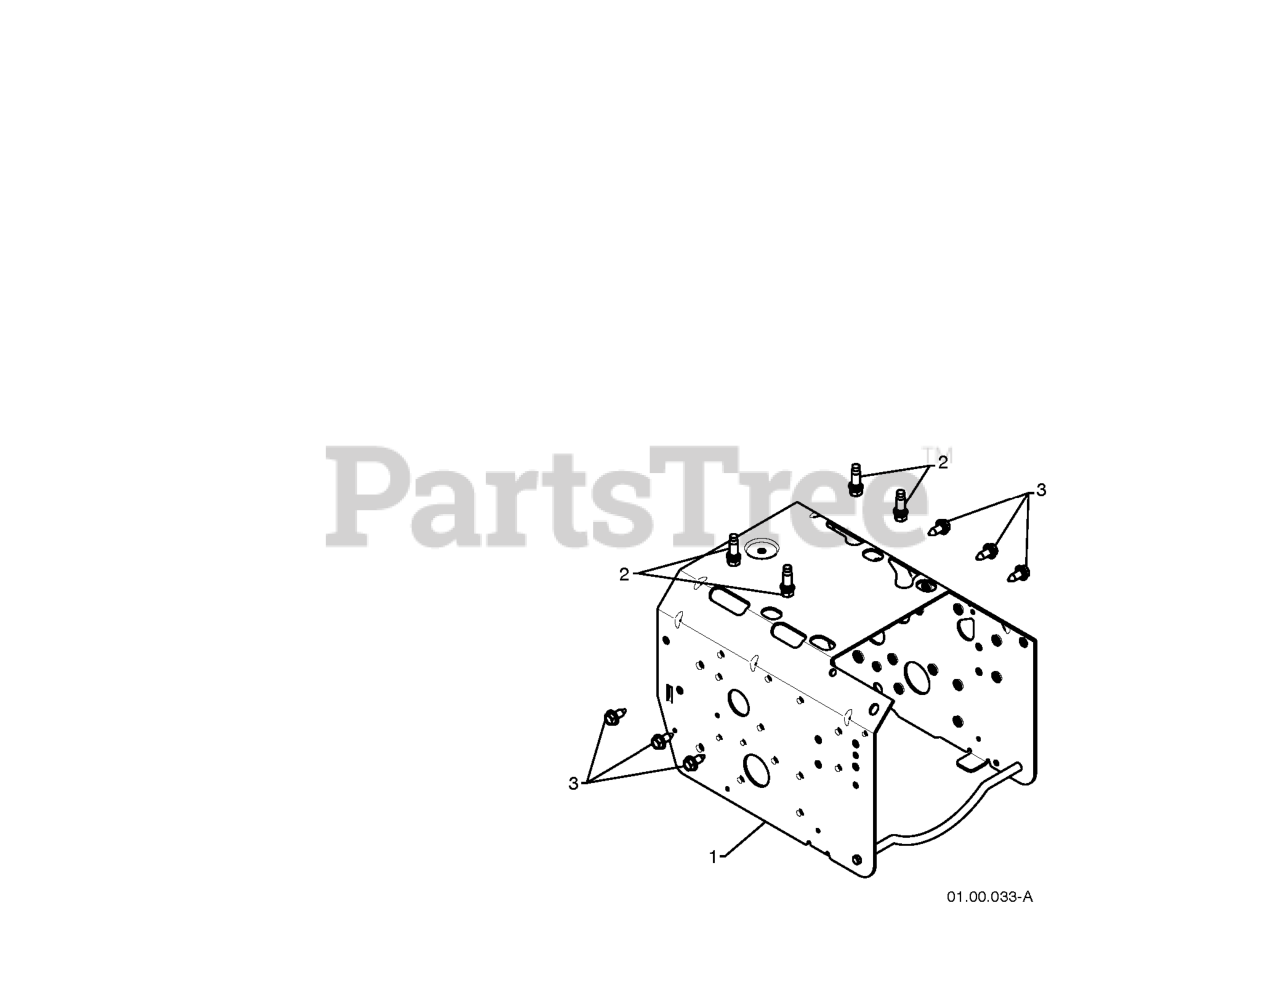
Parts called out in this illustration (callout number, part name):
1	FRAME.WELD.PNT.GEAR.ORANGE
2	BOLT 3/8-16X1-1/8
3	BOLT.HEX.HD.WASHER.5/16-18X.75
